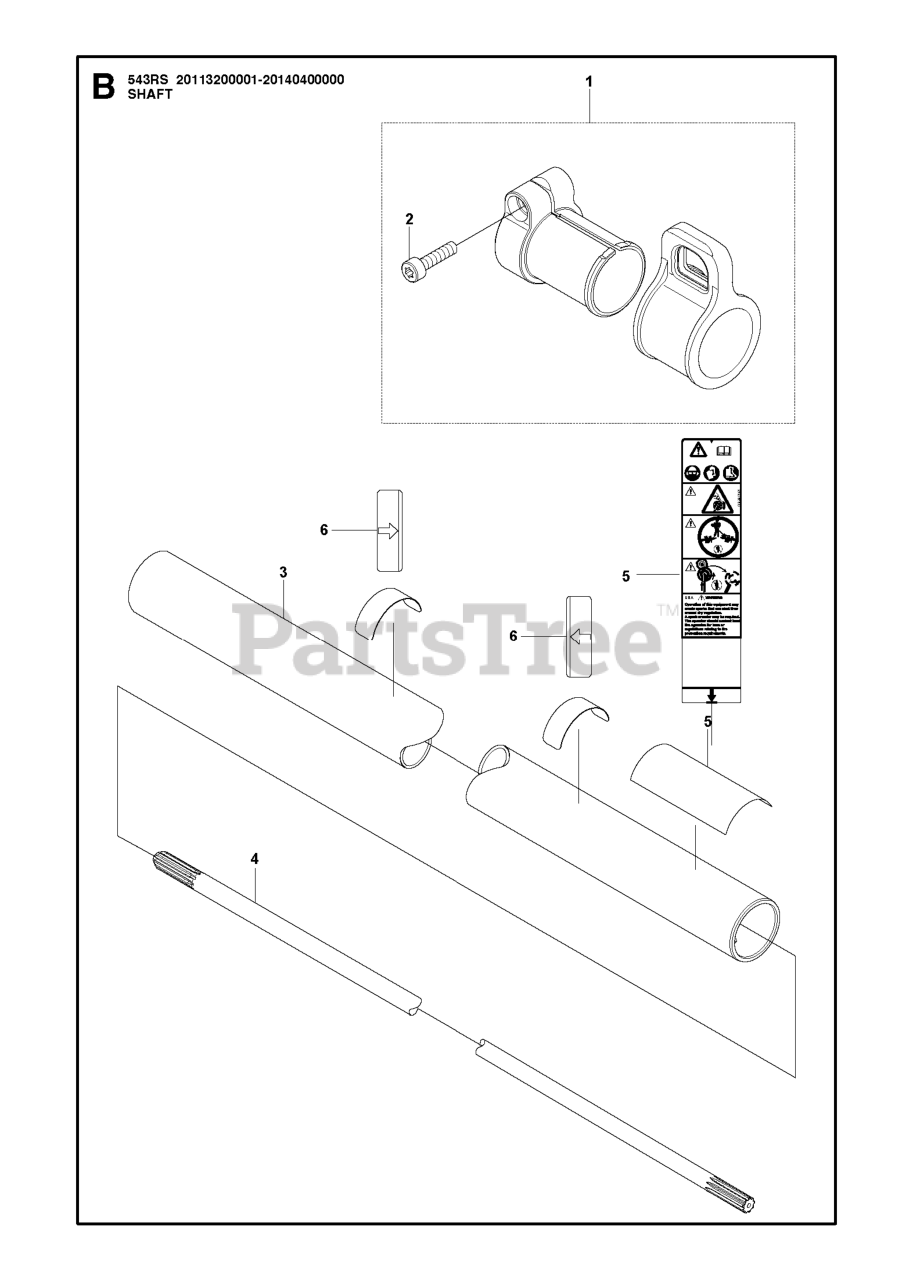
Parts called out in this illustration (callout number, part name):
1	HANGER ASSY.
2	BOLT
4	DRIVE SHAFT
5	LABEL WARNING TRIMMERS AND BRU
